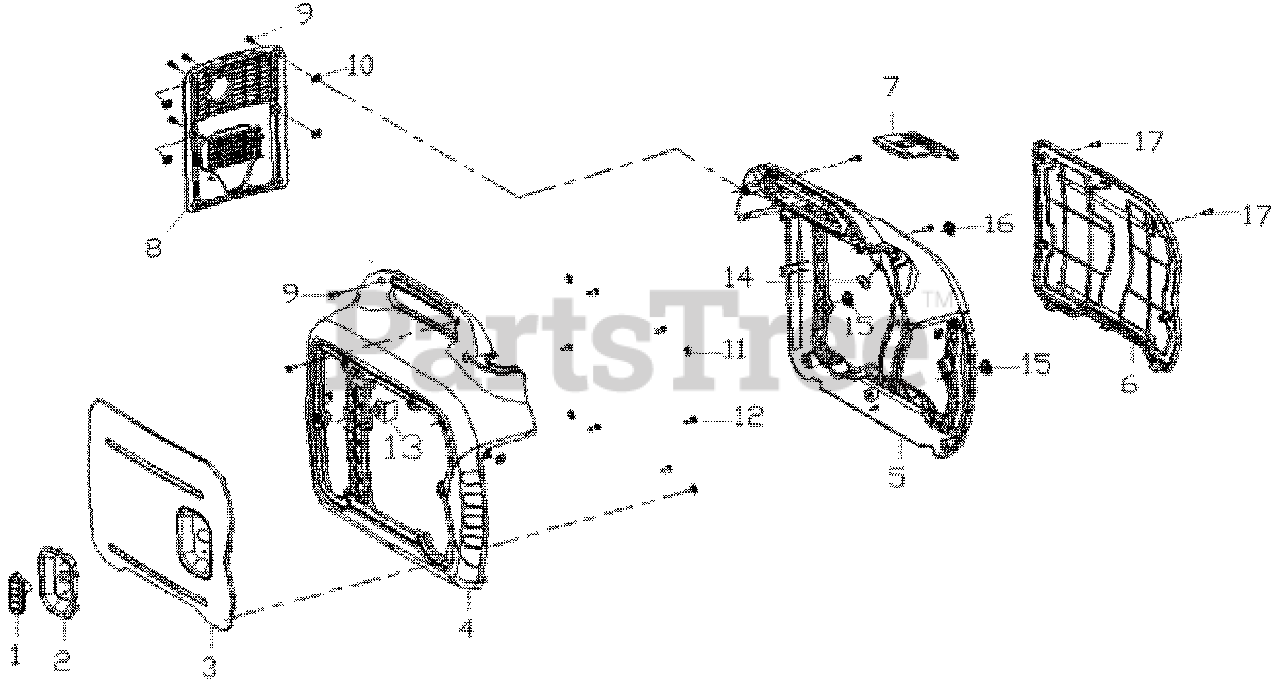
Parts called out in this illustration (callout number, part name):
2	LEASH HANDLE ADORNMENT HOOD
3	LEFT APPEARANCE COVER-GRAVELY
4	LEFT COLUMN
5	OUTER COLUMN
6	RIGHT APPEARANCE COVER-GRAVELY
7	SPARK PLUG MAINTENANCE COVER
8	SHUTTER
9	SCREW FLAT MAT COMBINATION
10	CLIP NUT
11	LOCK WASHER
12	SCREW, PAN, M4?15
13	BUFFER RUBBER
14	BUFFER RUBBER
15	RUBBER, FUEL TANK CUSHION
16	RUBBER, FUEL TANK CUSHION
